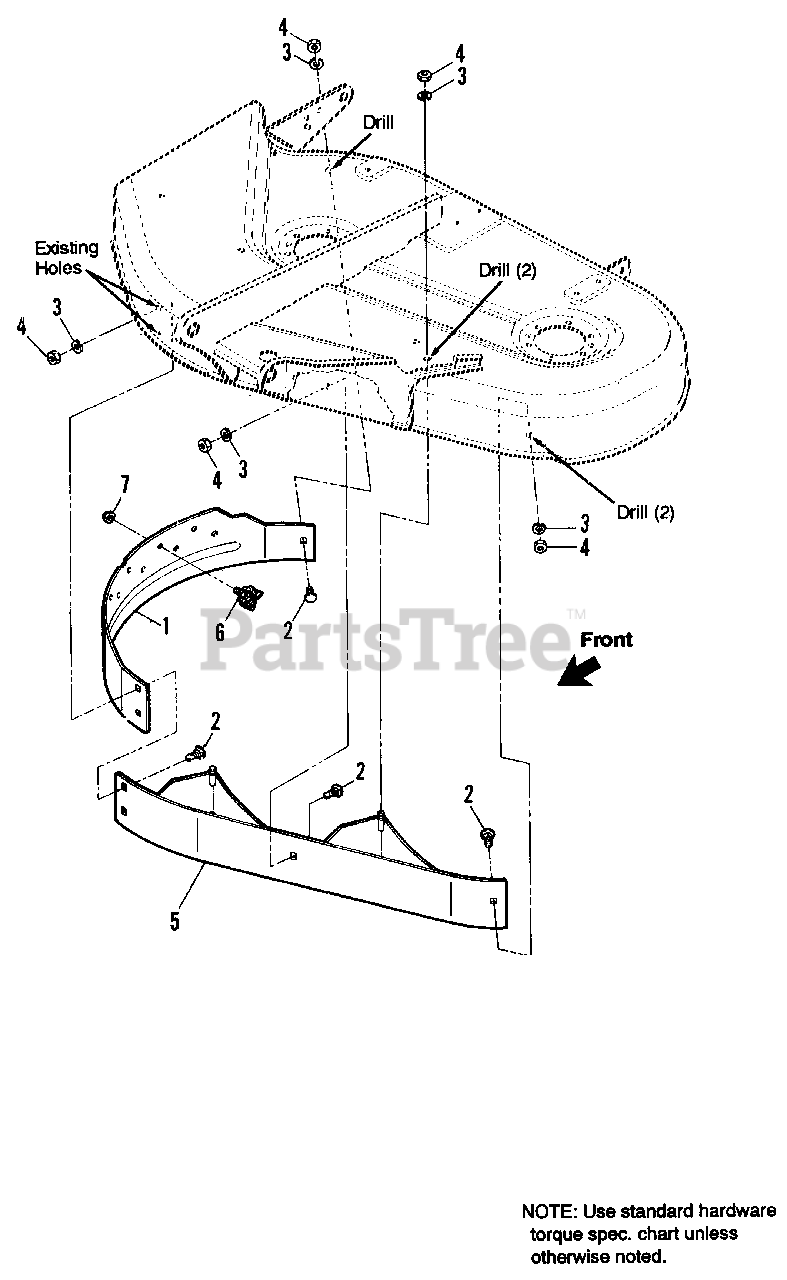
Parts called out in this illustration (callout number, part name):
1	BAFFLE, Discharge
2	CARRIAGE BOLT, 5/16-18 x 3/4
3	LOCKWASHER, 5/16
4	NUT, Hex, 5/16-18
5	BAFFLE, Mulching
6	SHREDDERS, Leaf
7	NUT, Hex, Plastite, 5/16-18
